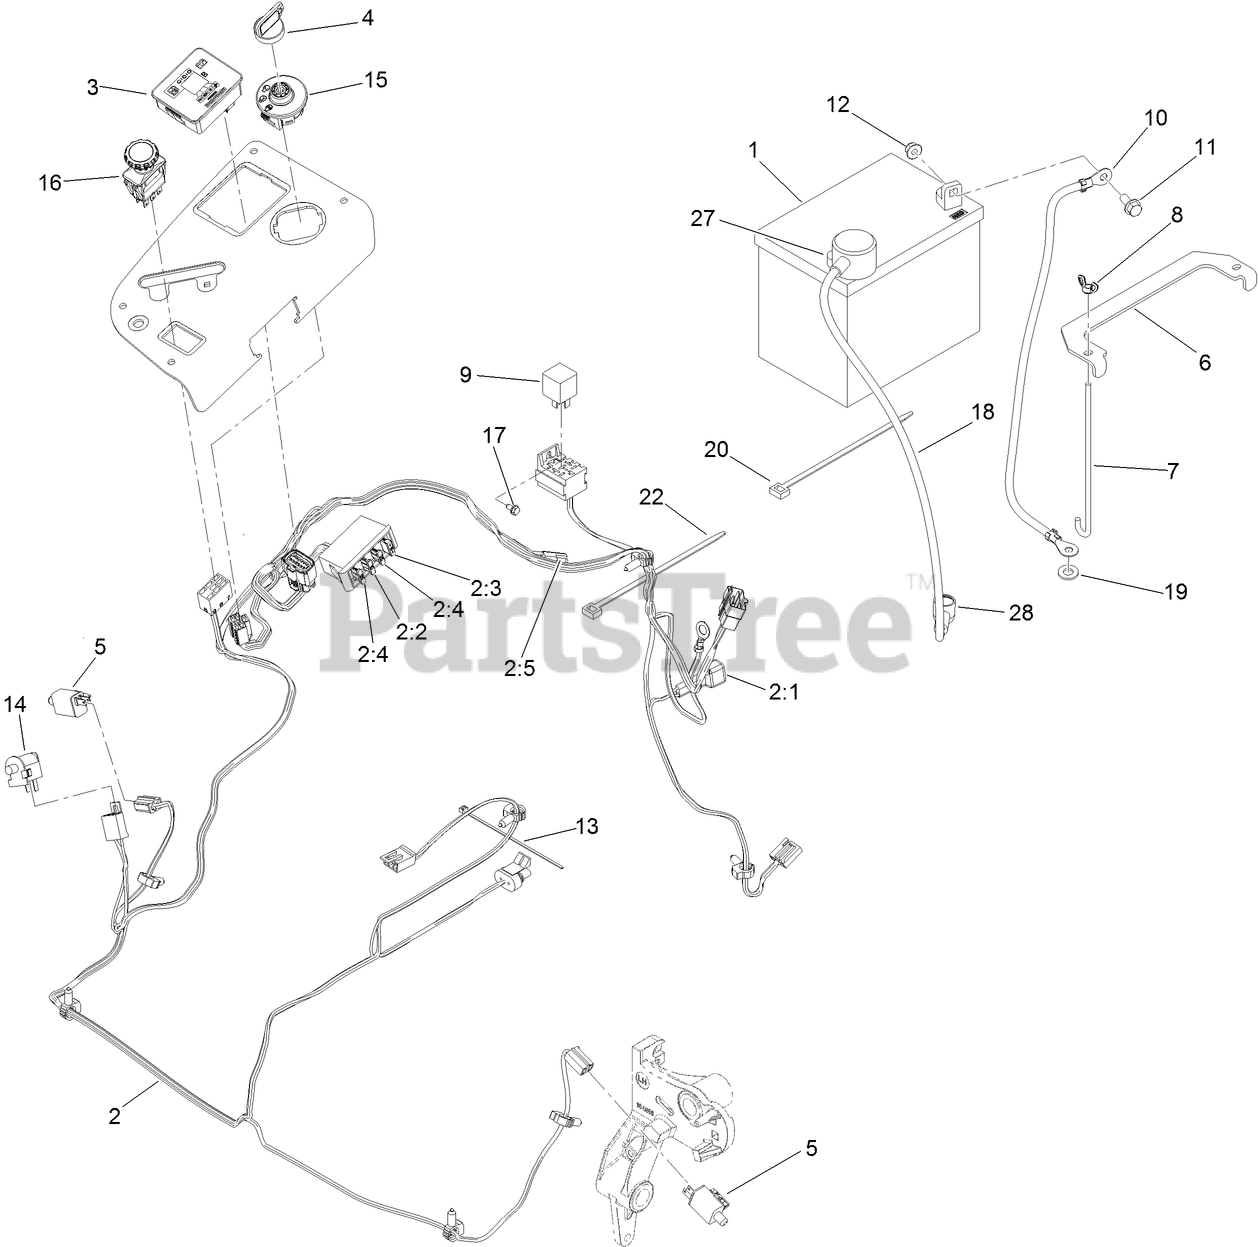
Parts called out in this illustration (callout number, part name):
1	BATTERY-DRY
2	HARNESS-WIRE, MAIN
2:2	FUSE-BLADE, 10 AMP
2:3	FUSE-BLADE, 15 AMP
2:4	FUSE-BLADE, 25 AMP
2:5	CAP-PLUG
3	FUEL/HOUR METER ASM
4	KEY-IGNITION
5	SWITCH
6	STRAP-TIE DOWN, BATTERY
7	BOLT-HOLDDOWN
8	WINGNUT
10	CABLE-BATTERY, NEGATIVE
11	SCREW-HHF
12	NUT-HF, NI
13	TIE-CABLE
14	SWITCH-BAIL
15	SWITCH-IGNITION
16	SWITCH-PTO, 10 AMP
17	SCREW-HWH
18	CABLE-BATTERY, POSITIVE
19	WASHER-FLAT
20	TIE-PLASTIC
22	TIE-PLASTIC
27	INSULATOR-BATTERY
28	INSULATOR-SOLENOID
